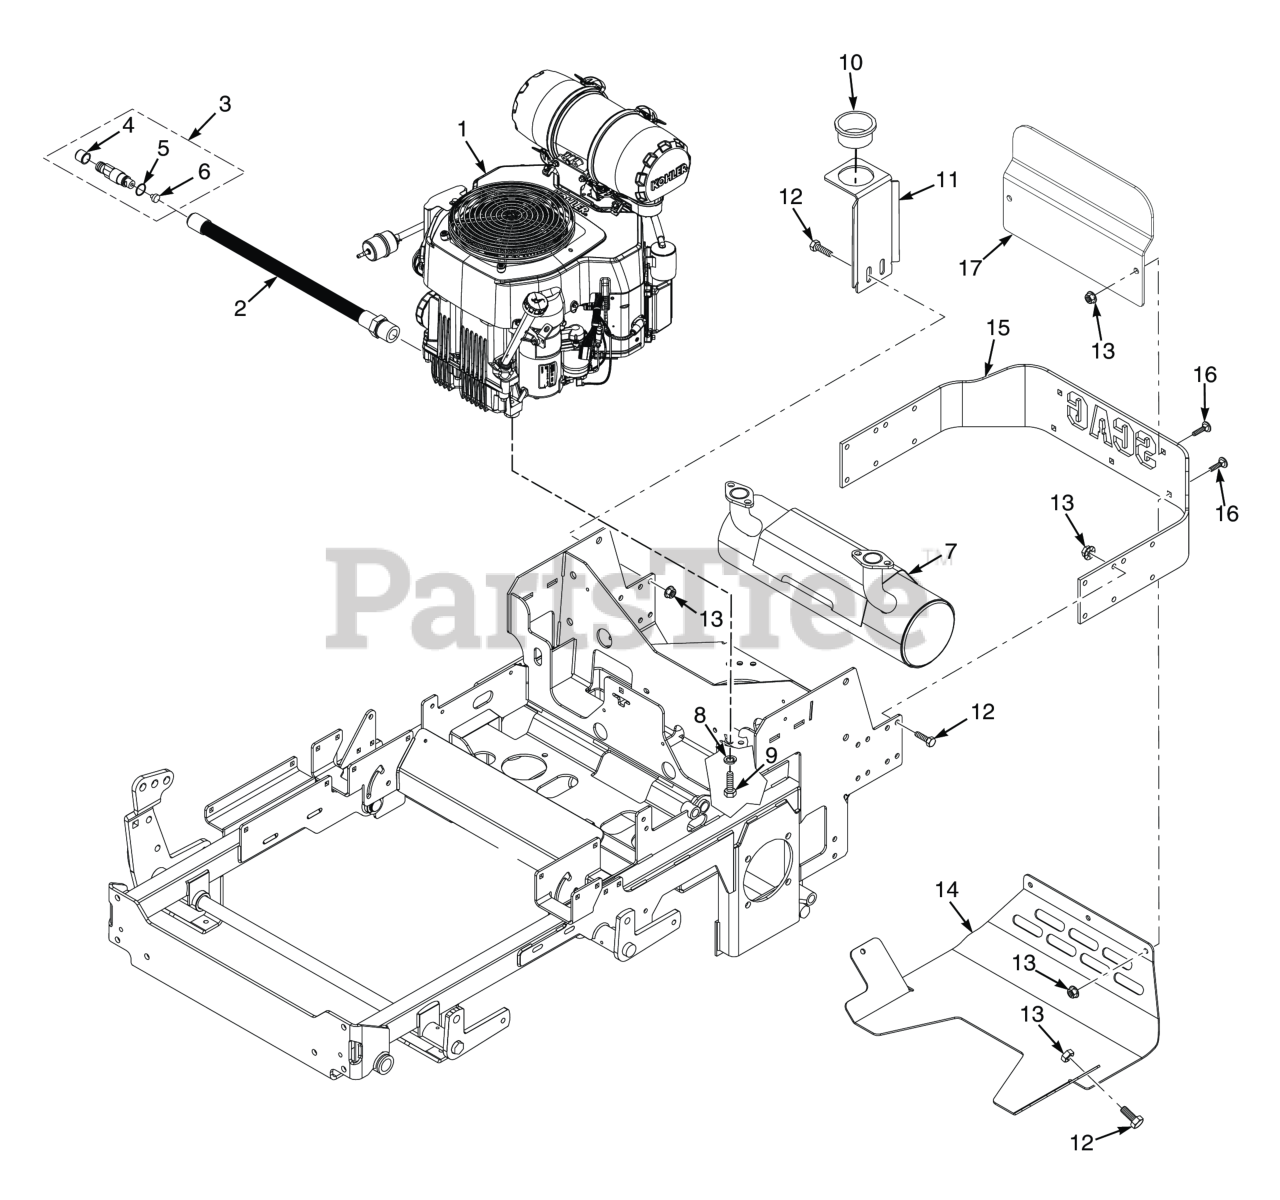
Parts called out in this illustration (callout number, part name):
1	Engine, 22 HP Kawasaki FX
1	Engine, Kawasaki 26FT-EFI
1	Engine, Kohler 25CV-EFI
1	Engine, Briggs and Stratton 32BV
2	Hose Assembly, Engine Oil Drain - Kawasaki FS/FX
2	Hose, Oil Drain - Kohler CV & CV-EFI
2	Hose, OIl Drain, Briggs & Stratton
3	Valve Assembly, Oil Drain
4	O-Ring
5	O-Ring
7	Muffler, Kawasaki FS/FX
7	Muffler, Kohler 25CV-EFI & 26CV-EFI
7	Muffler, Briggs and Stratton 32BV
8	Lockwasher, 3/8" Spring, Kawasaki FX / FS
9	Bolt, Hex Head 3/8-16 x 1-1/4", Kawasaki FX / FS
9	Bolt, Hex Head Self-Tap 3/8-16 x 1-1/4" (Kohler x3 - 25EFI, Kohler x4 - 29EFI)
10	Bushing, Thick Panel Snap
11	Bracket, Oil Drain Hose
12	Bolt, Hex Head, 3/8-16 x 1 Gr. 5
13	NUT, 3/8-16 SERRATED FLANGE HEX HEAD
14	Plate, Skid
15	Bumper, Rear
16	Carriage Bolt, 3/8-16 x 1.0"
17	Guard, Engine
